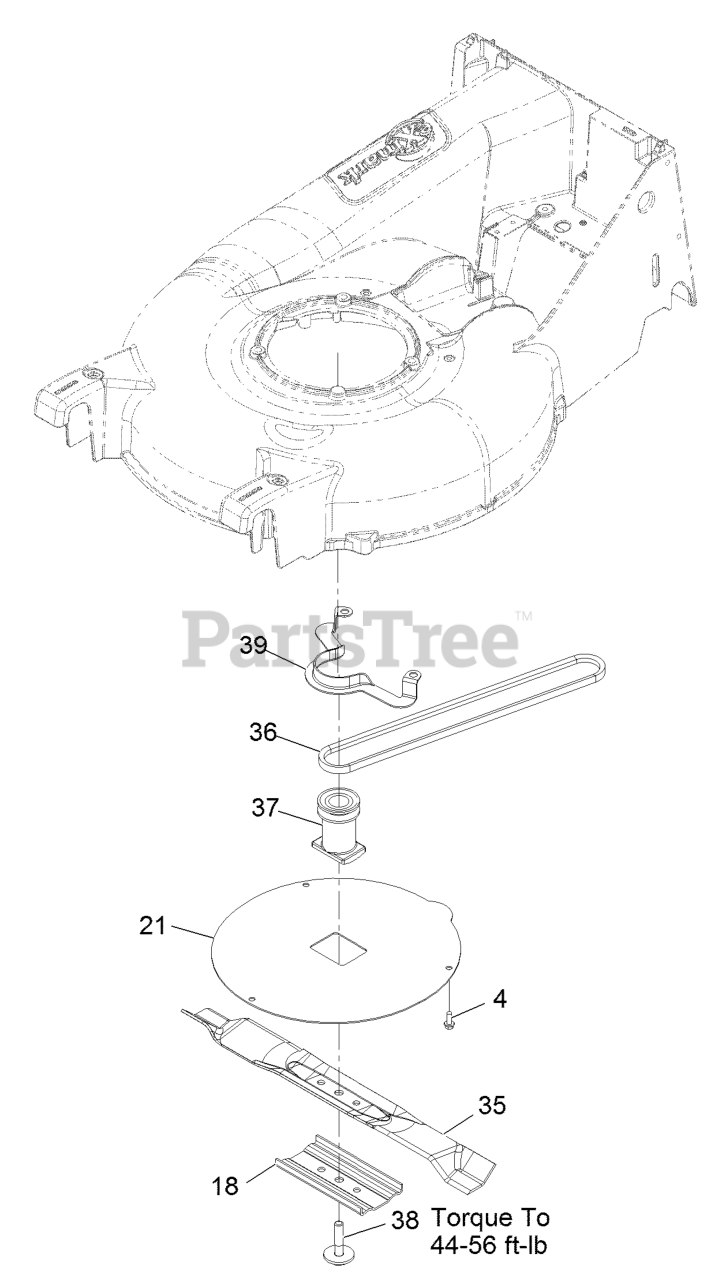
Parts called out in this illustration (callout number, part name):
4	SCREW-HWH
18	SUPPORT-BLADE
36	BELT,3L P21 DRIVE
37	BLADE-ADAPTER
38	BOLT-BLADE, SEM
39	GUIDE-BELT
